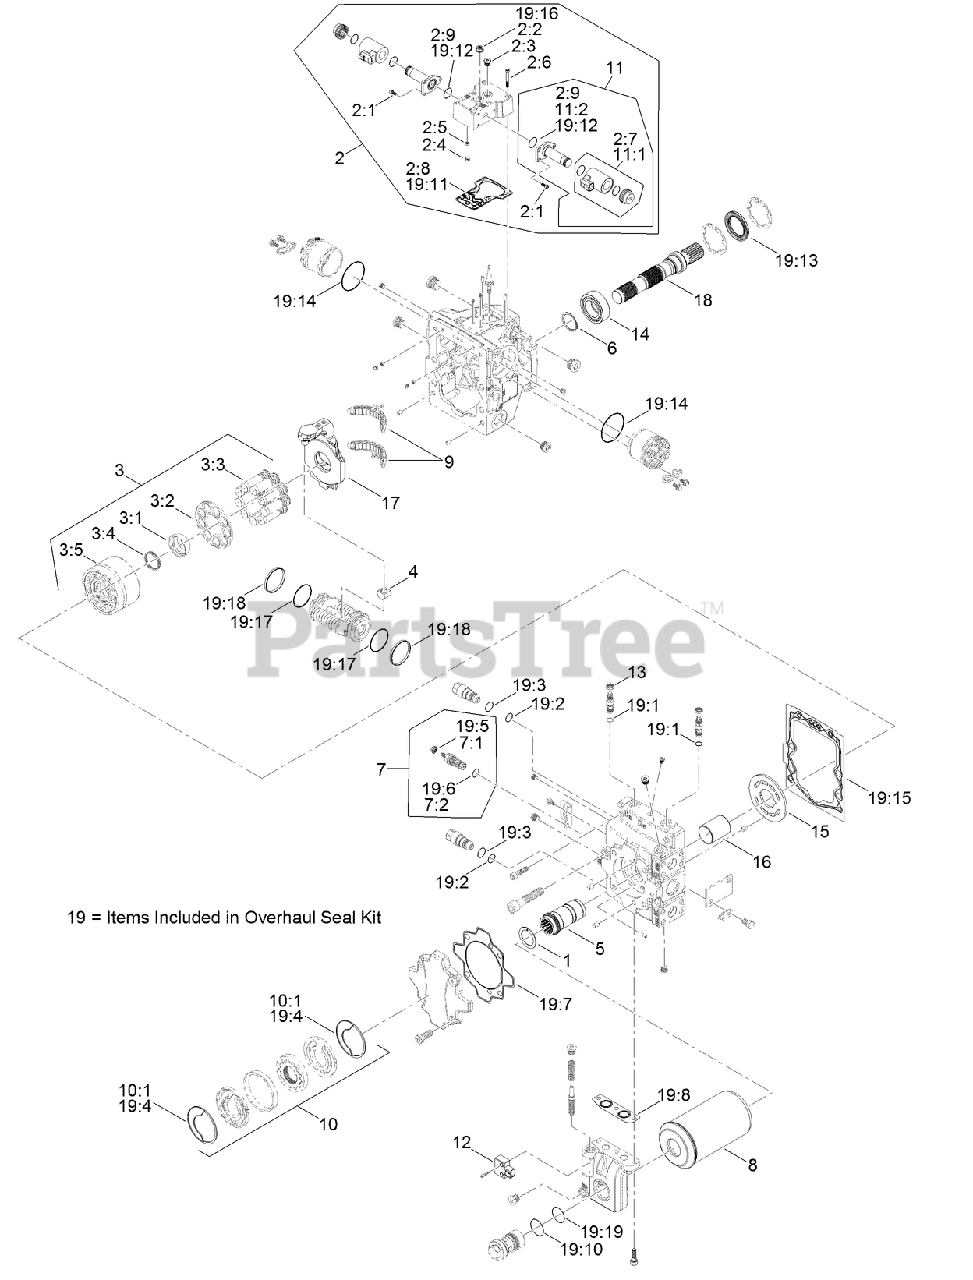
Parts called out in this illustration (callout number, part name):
1	PLATE-THRUST
2	CONTROL KIT (12 VOLT)
2:2	NUT-SEAL
2:4	SCREEN
2:5	RING-LOCKING
2:7	COIL KIT
2:8	GASKET-CONTROL
2:9	O-RING
3	CHECK VALVE KIT
3:1	GUIDE-BALL, SLIPPER RETAINER
3:2	GUIDE-SLIPPER
3:3	PISTON ASM
3:4	RING-SPRING
3:5	CYLINDER BLOCK ASM
4	BLOCK-SLIDER
6	RING-RETAINING
7	CHARGE RELIEF VALVE KIT
7:1	NUT-SEAL
7:2	O-RING
8	FILTER
9	SWASHPLATE BEARING KIT
10	CHARGE PUMP KIT (14CC)
10:1	RING-SEAL
11	SOLENOID VALVE ASM
11:1	COIL KIT
11:2	O-RING
12	SENSOR-FILTRATION
14	BEARING-BALL
15	PLATE-VALVE, CW
16	BEARING-JOURNAL
17	SWASHPLATE
19	OVERHAUL SEAL KIT
19:1	O-RING
19:2	O-RING
19:3	O-RING
19:4	RING-SEAL
19:5	NUT-SEAL
19:6	O-RING
19:7	SEAL-ADAPTER
19:8	GASKET-ADAPTER, FILTER
19:10	O-RING
19:11	GASKET-CONTROL
19:12	O-RING
19:13	SEAL-LIP
19:14	O-RING
19:15	GASKET-CAP, END
19:16	NUT-SEAL
19:17	O-RING
19:18	RING-PISTON
19:19	O-RING
